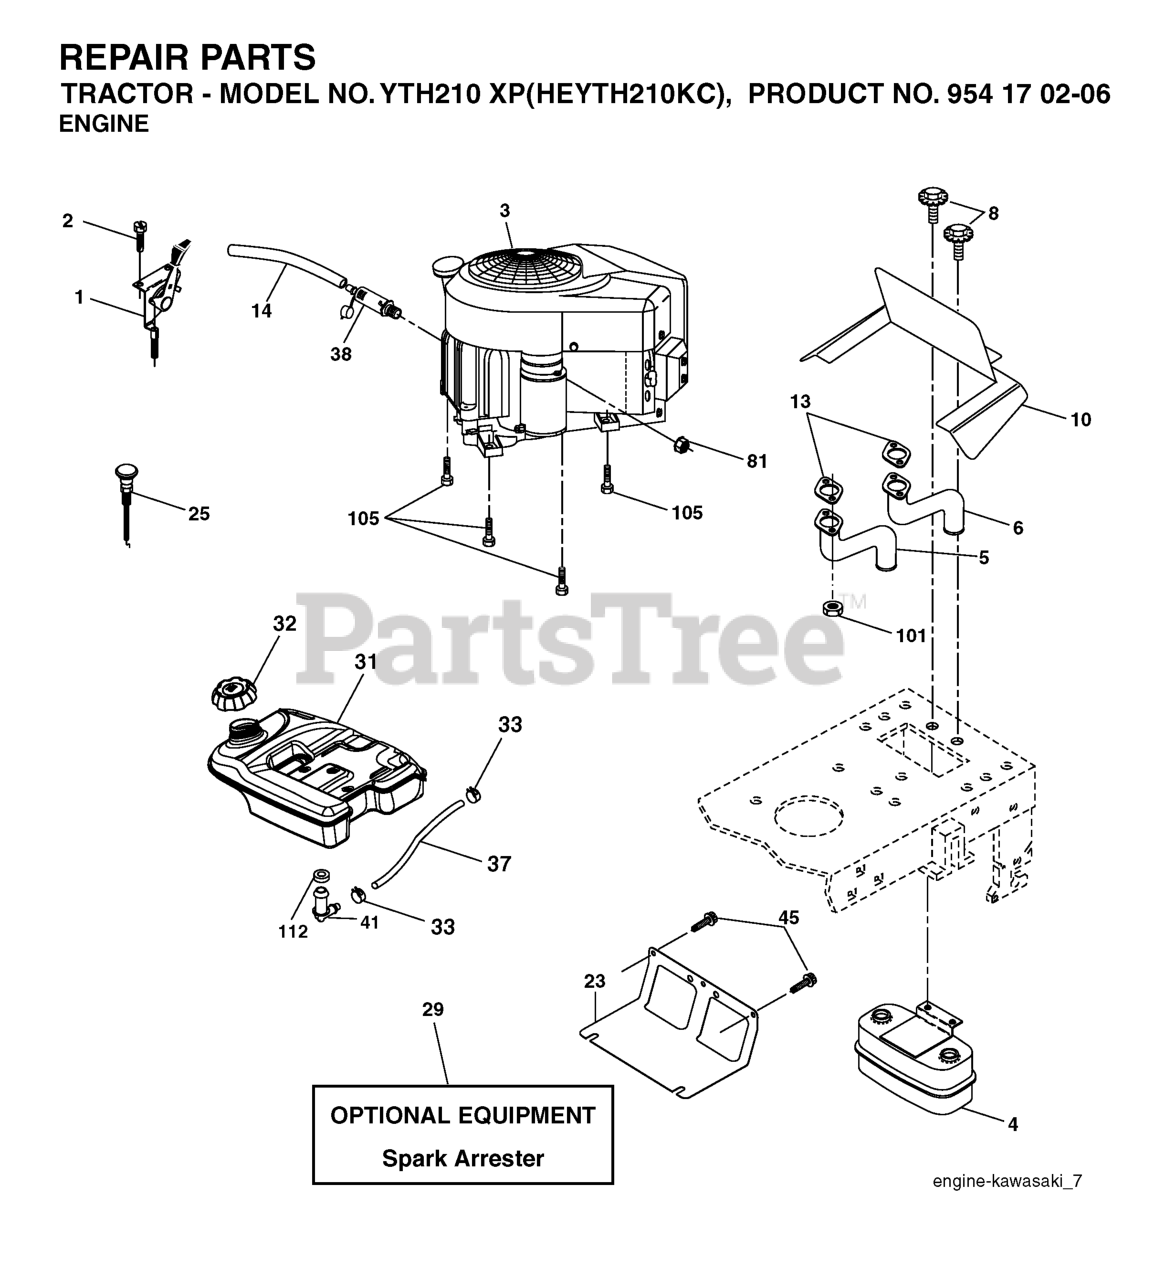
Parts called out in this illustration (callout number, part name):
2	SCREW
4	MUFFLER.TWIN.CYL.LOW.TONE
5	TUBE EXHAUST LH
6	EXHAUST.TUBE.RH.KAWA
8	BOLT.5/16-18UNCX3/4 W/SEMS.BLK
10	RP SHIELD HEAT MUFFLER
14	TUBE, DRAIN OIL ASM.
23	SHIELD.BROWNING.DBR.GUARD
25	CONTROL, CHOKE, 37", PUSH
26	Nut Keps 3/8 - 24 UNF
29	KIT.SPARK ARRESTOR 794945 B&S
31	4.0 REAR FUEL TANK
32	TANK CAP
33	HOSE CLAMP
37	REPL BY 532 00 85-43
41	STEM FUEL TANK
45	SCREW, 3/8-16X3/4
81	NUT
101	NUT.HEX.FLANGE.TOPLOCK
105	SCREW 3/8-16X1
112	BUSHING OUTLET T
